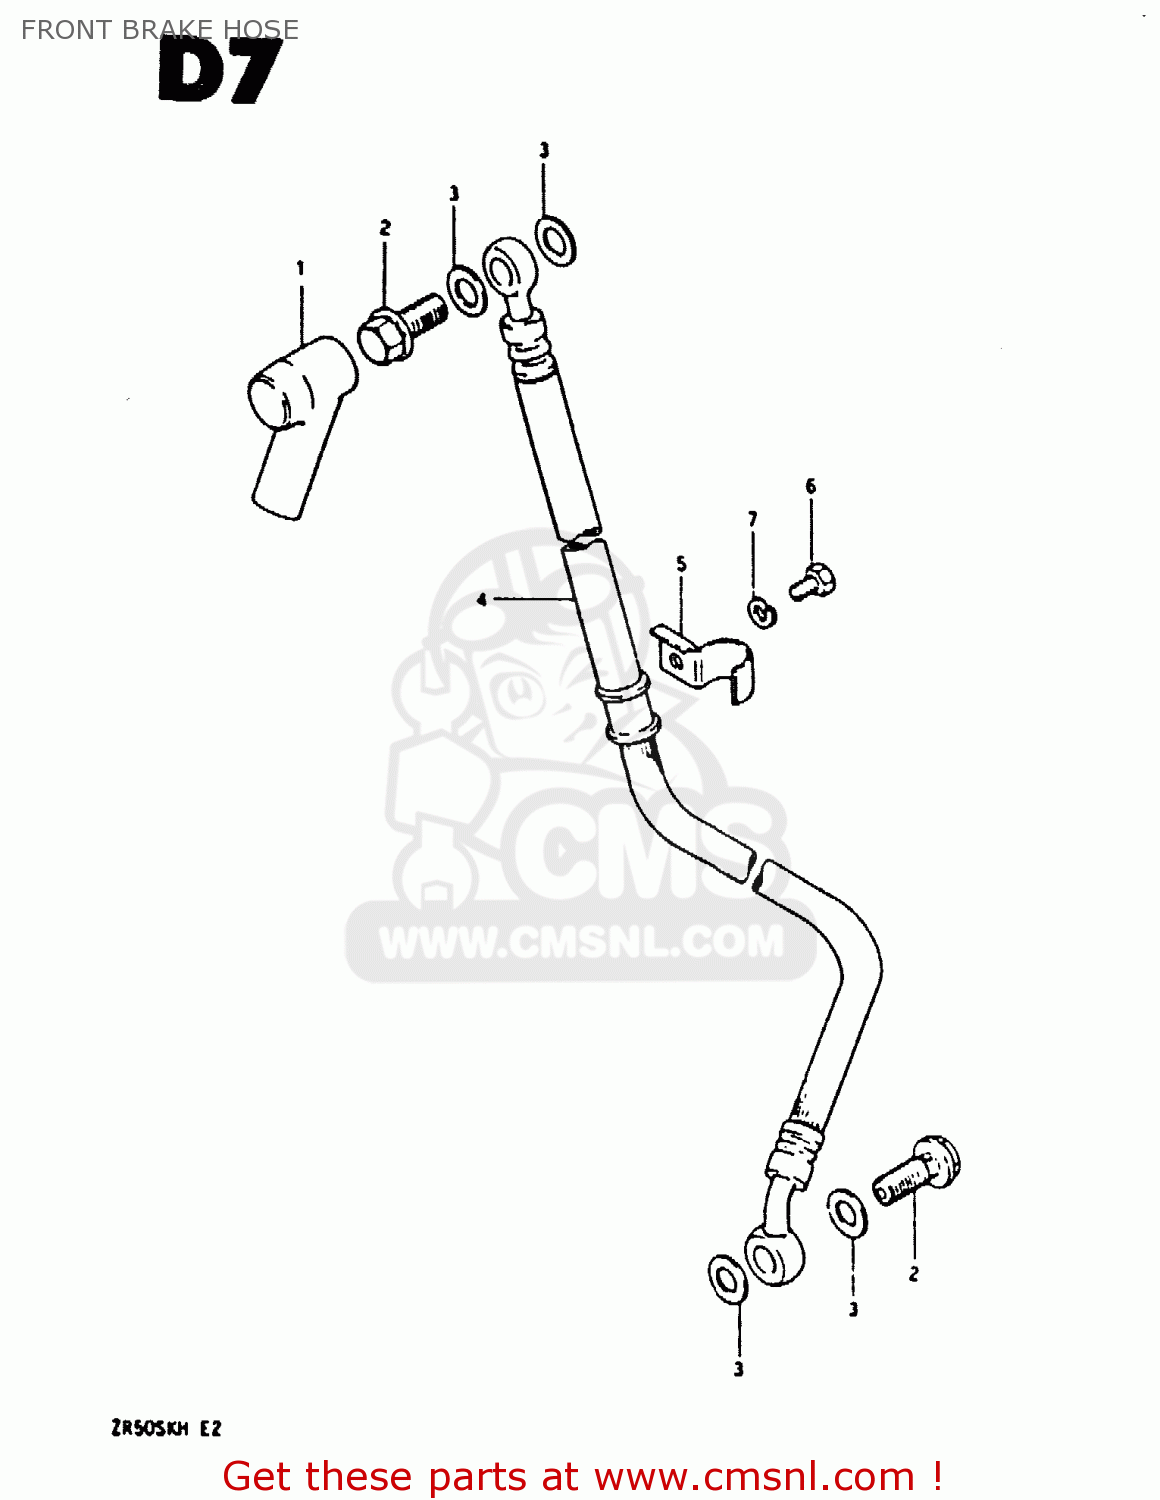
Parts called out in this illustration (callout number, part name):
1	BOOT,MASTER CYLINDER
2	BOLT UNION
3	WASHER(10X15X1.5)
4	HOSE, BRAKE
5	CLAMP
6	BOLT
7	WASHER,LOCK
